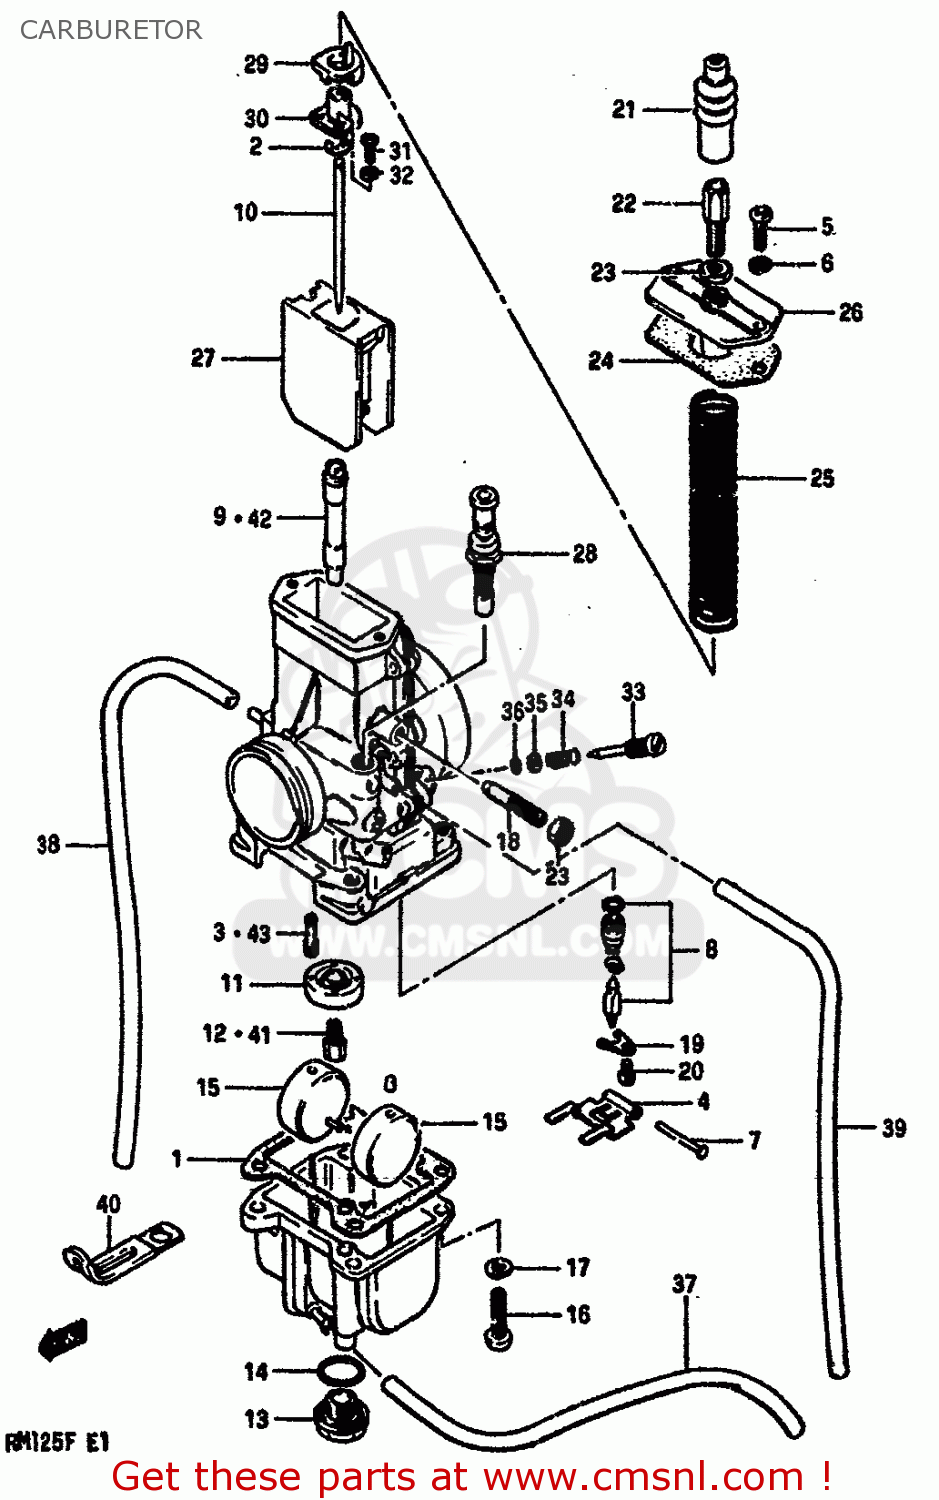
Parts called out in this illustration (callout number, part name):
1	GASKET,FLOAT CAHMBER (NAS)
2	CLIP
3	JET,PILOT(45)
4	ARM,FLOAT
5	SCREW
6	LOCK WASHER
7	PIN,FLOAT
8	VALVE ASSEMBLY,NEEDLE
9	JET
10	NEEDLE JET
11	RING,MAIN JET FIXING
12	JET
13	SCREW,GUIDE
14	O RING,DRAIN PLUG
15	FLOAT
16	SCREW
17	LOCK WASHER
18	SCREW,THROTTLE SCREW
19	PLATE
20	SCREW
21	CAP,CABLE ADJUSTER
22	ADJUSTER,CABLE
23	NUT
24	GASKET,TOP (NAS)
25	SPRING,THROTTLE VALVE
26	CAP,CARBURETOR,TOP
27	VALVE,THROTTLE
28	PLUNGER ASSEMBLY
29	RING
30	JOINT
31	SCREW
32	LOCK WASHER
33	SCREW,PILOT AIR
34	SPRING,THROTTLE SCREW
35	GASKET
36	O-RING
37	HOSE
38	HOSE
39	HOSE
40	CLAMP L:35
41	JET
42	JET,NEEDLE
43	JET
